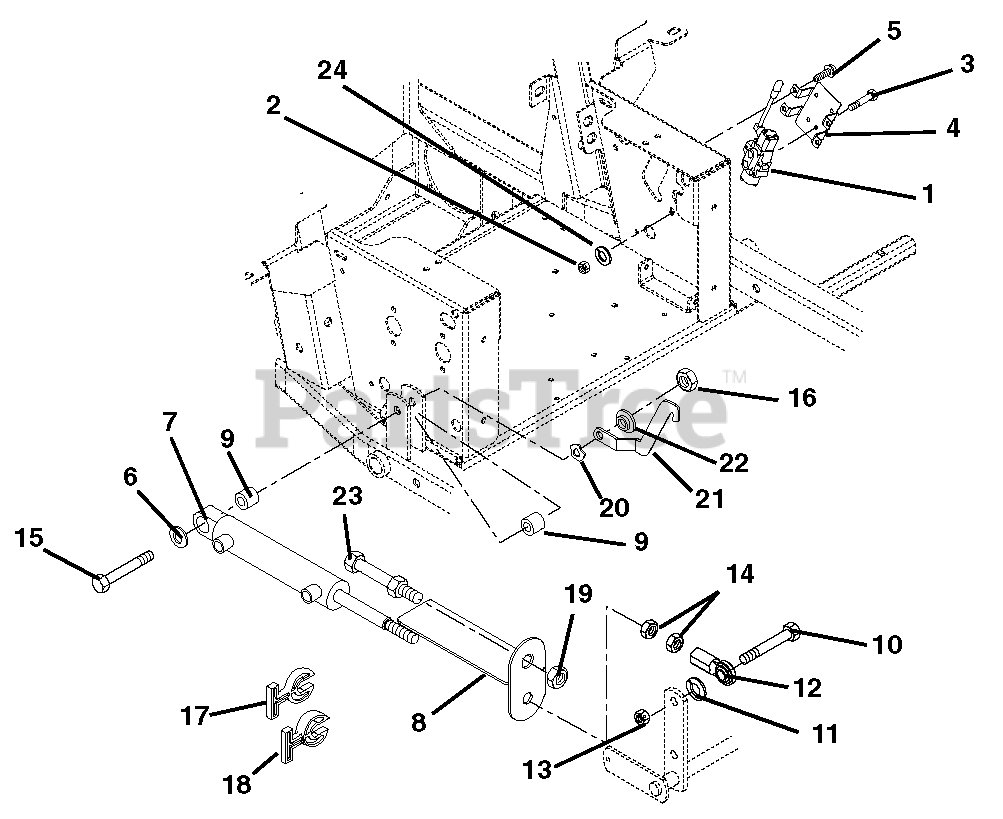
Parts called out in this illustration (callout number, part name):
1	Valve, Hydraulic
2	Nut, Locking Center .31-18
3	Bolt, Hex .31-18 x 2.00 Grade 5
4	Bracket, Valve Mounting
5	Screw, Tapping .38-16 x .50 Hex Washer Head
6	Washer, Flat Steel .515 x 1.625 x .25
7	Cylinder, Lift
8	Strap, Height of Cut Indicator
9	Bushing .516 x 1.00 x 1.05
10	Bolt, Hex .62-11 x 2.25 Grade 8
11	Washer, Lock .62 x .156
12	Rod End, Right Hand Female .625
13	Nut, Locking Center .62-11
14	Nut, Jam .625-18
15	Bolt, Hex .50-13 x 3.75 Grade 5
16	Nut, Locking Top Flange .50-13
17	Stop, Cylinder .34 Thick
18	Stop, Cylinder .68 Thick
19	Nut, Jam .75-16
20	Washer, Wave .076 x 1.12 x .08
21	Latch, Floor Board
22	Bushing, Flange .515 x .75 x .275 x 1.12
24	Washer, Lock .31 x .078 Reg
